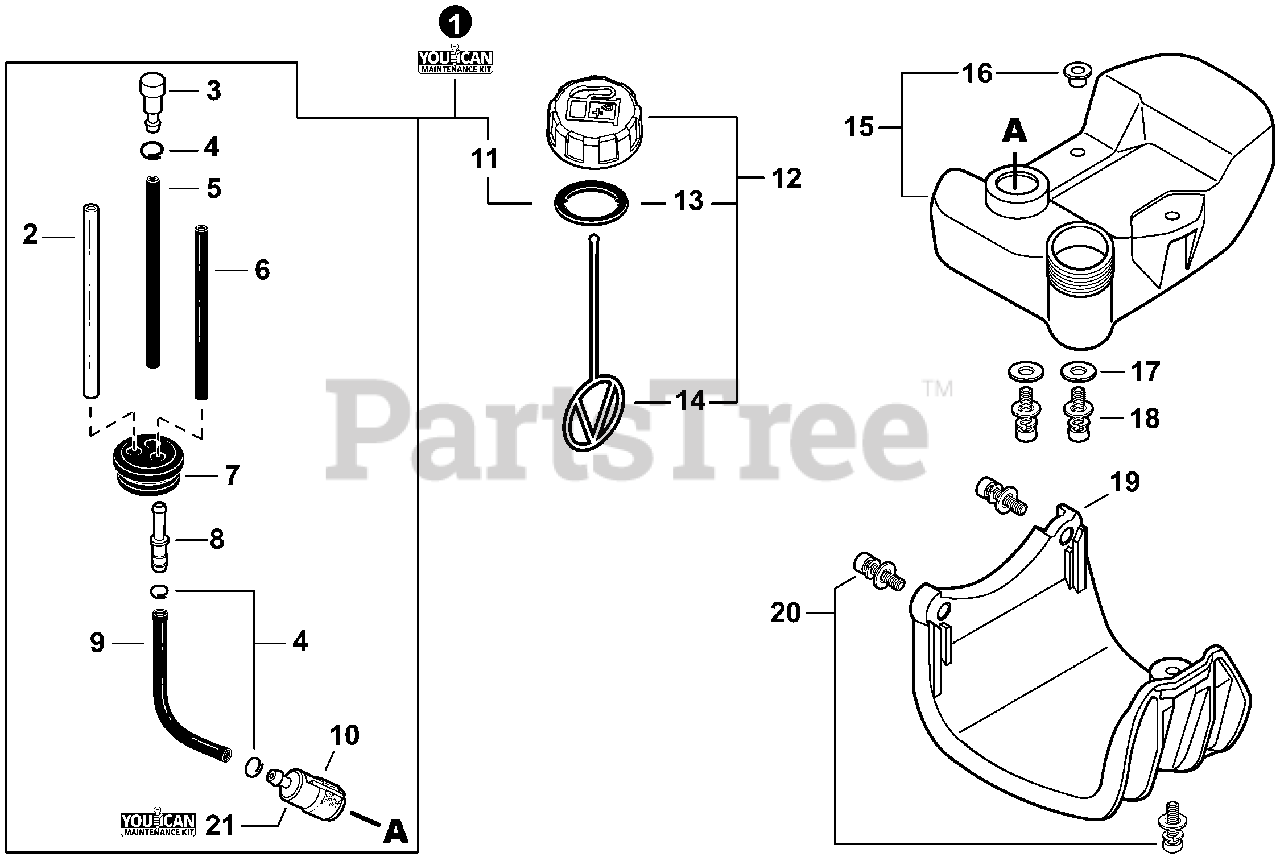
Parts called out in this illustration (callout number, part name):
1	FUEL SYSTEM KIT - YOUCAN™
2	PIPE, FUEL 3×6×80 CLEAR
3	VENT ASSY
4	CLIP Ø6.5 MM
5	PIPE 3×6×115 BLACK
6	PIPE, FUEL 3×5×74 BLACK
7	GROMMET, FUEL
8	CONNECTOR, PIPE Ø5ר3.5
9	PIPE, FUEL 3×6×100
10	FILTER, FUEL
11	GASKET, FUEL CAP
12	CAP ASSY, FUEL
13	GASKET, FUEL CAP
14	CONNECTOR, CAP L= 100 MM
15	TANK, FUEL
16	COLLAR 5
17	WASHER 5.5×12×0.8
18	BOLT 5×18
19	GUARD, FUEL TANK
20	BOLT 5×22
21	TUNE-UP KIT - YOUCAN™
